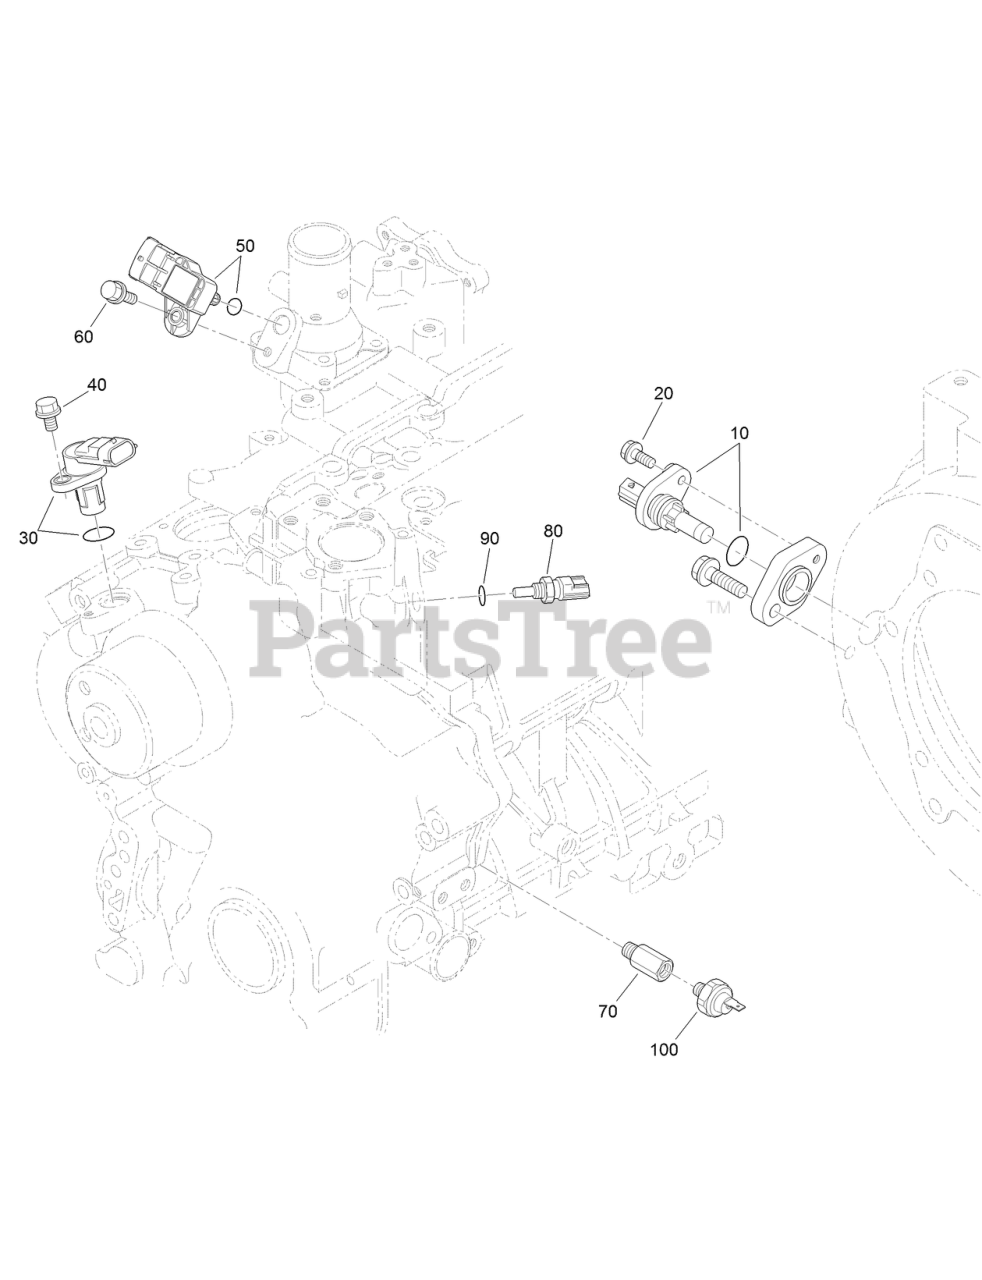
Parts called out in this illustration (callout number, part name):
10	SENSOR
20	BOLT-FLANGE
30	SENSOR
40	BOLT-FLANGE
50	SENSOR-BOOST
60	BOLT-FLANGE
70	ADAPTER-SWITCH, OIL
80	SENSOR-TEMPERATURE, WATER
90	O-RING
100	SWITCH-OIL
